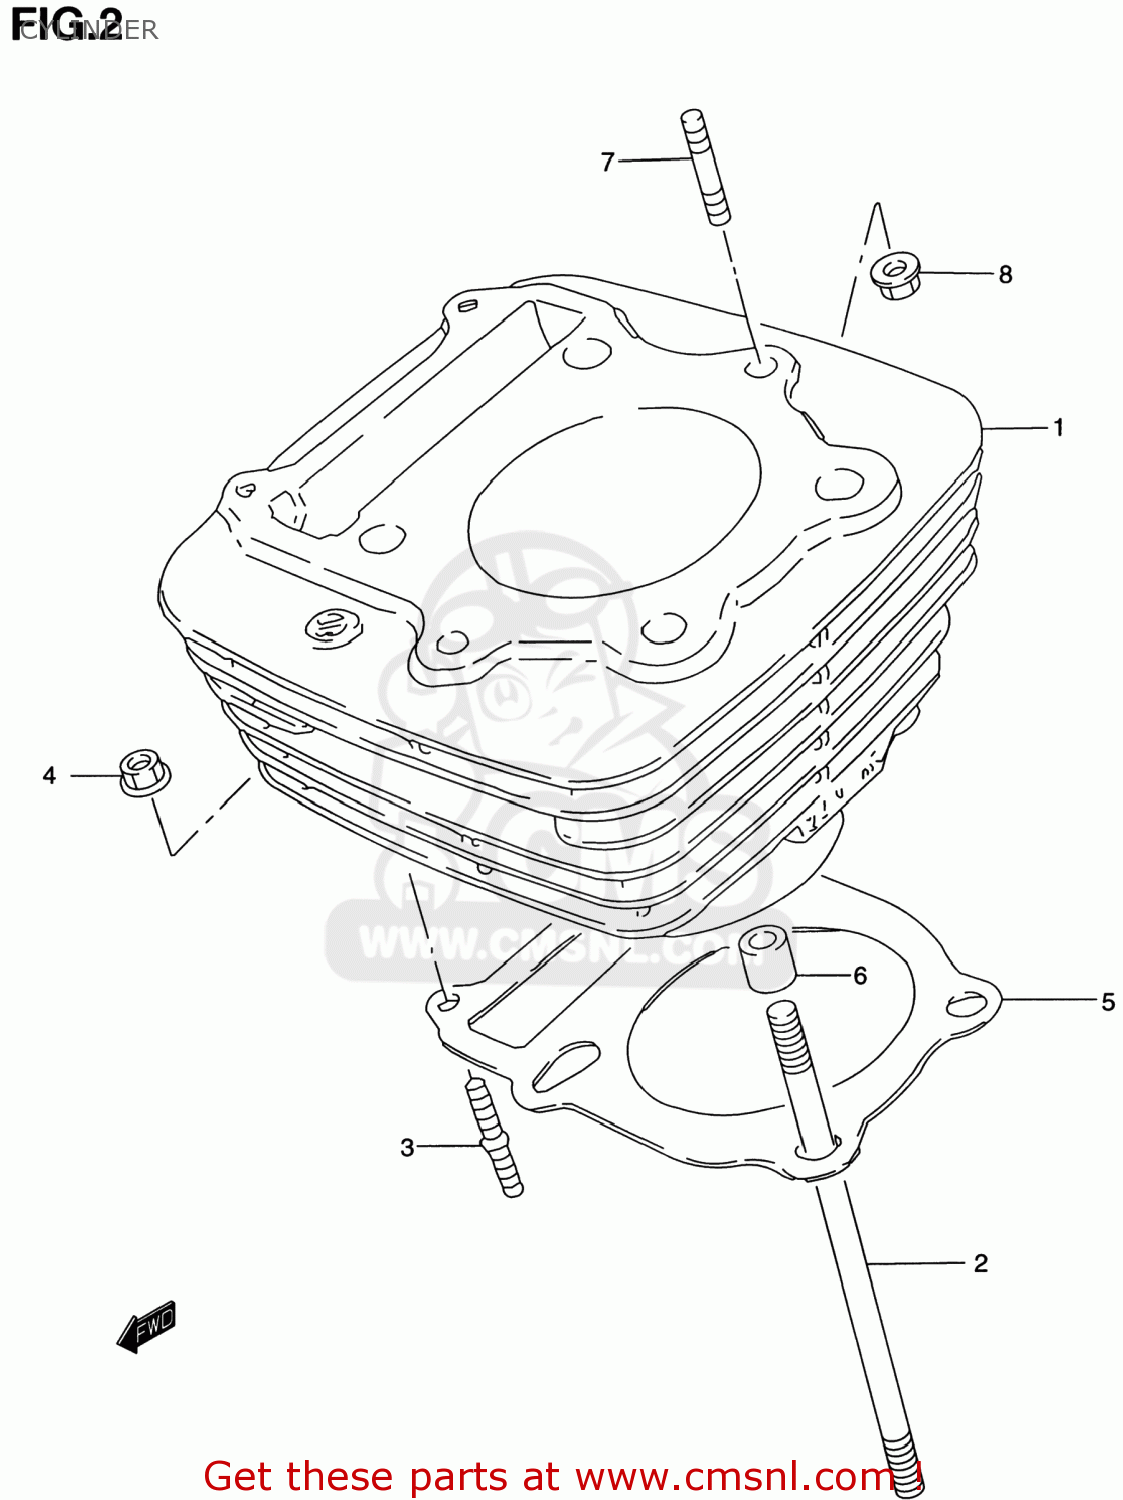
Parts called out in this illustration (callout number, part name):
1	CYLINDER
2	BOLT,STUD
3	STUD 6X20
4	NUT
5	GASKET,CYLINDER (NAS)
6	PIN
7	BOLT,STUD
8	NUT
